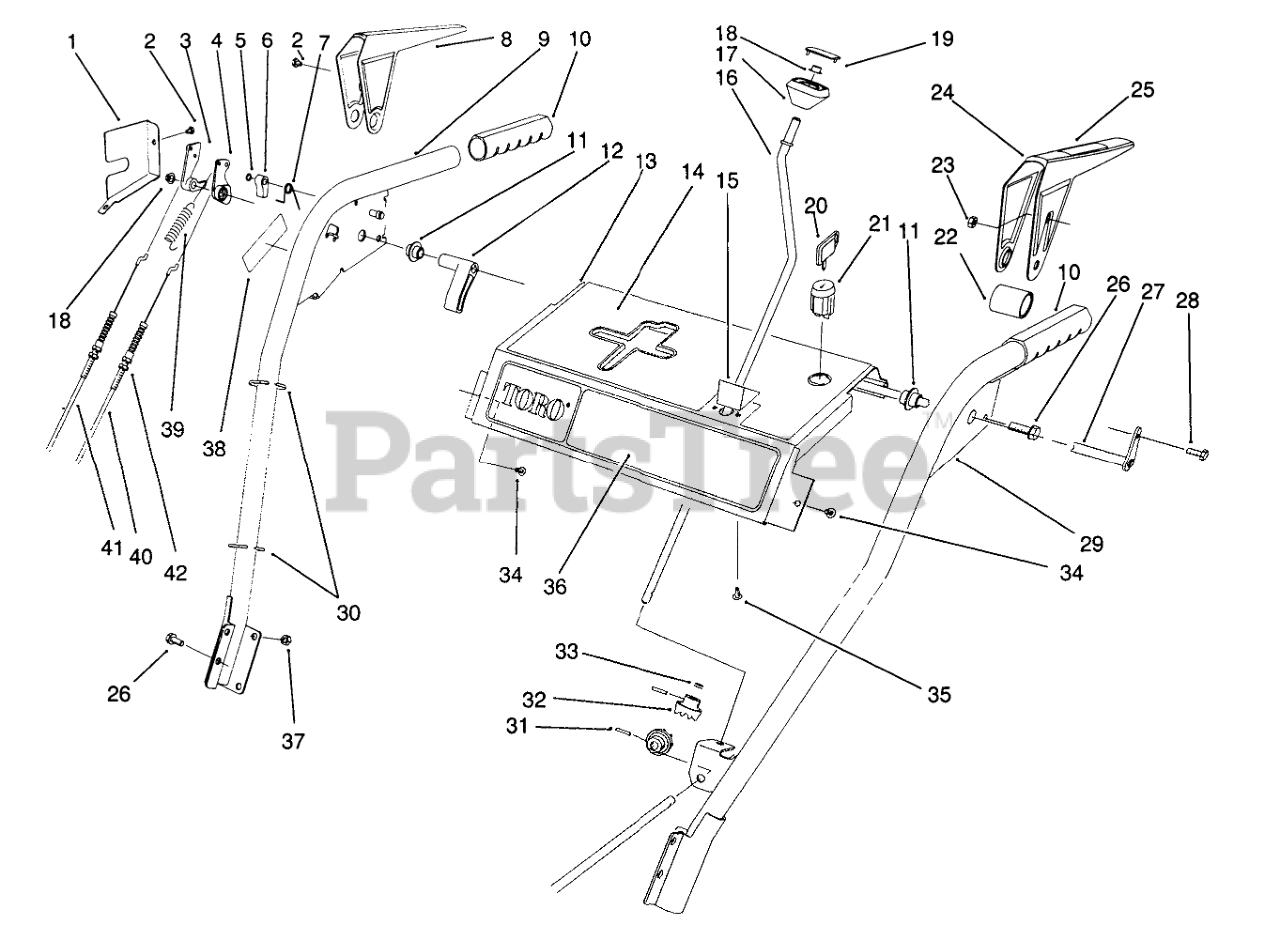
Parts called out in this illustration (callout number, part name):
1	Cover Lever Lock
2	SCREW-HH
3	TANG-LOCKING
4	CAM-RELEASE
5	E-RING-RETAINER
6	LATCH-LOCKING
7	SPRING-TORSION
8	Lever-Impeller
9	Handle-R.H.
10	GRIP-HANDLE
11	BUSHING-LEVER
12	LEVER-TRIP
13	Panel-Control
14	Decal-Panel, Top
15	PLATE-GUIDE
16	CRANK-ROD, CHUTE
17	KNOB-CONTROL, CHUTE
18	RETAINER-PUSH ON
19	COVER-KNOB
20	KEY-IGNITION
21	SWITCH
22	SPACER-LEVER, TRACTION
23	NUT-LOCK, NI
24	Lever-Traction
25	DECAL-LEVER
26	SCREW-HHF
27	CROSS ROD ASM
28	SCREW-HWH
29	Handle-L.H.
30	TIE-CABLE
31	PIN-SPRING
32	GEAR-UNIVERSAL
33	WASHER-RUBBER
34	SCREW-HWHTF
35	SCREW-PPH
36	DECAL-FRONT PANEL (828)
37	NUT-LOCK, NI
38	DECAL-WARNING
39	Spring-Extension
40	CABLE-TRACTION
41	CABLE-IMPELLER
42	NUT-LOCK, NI
